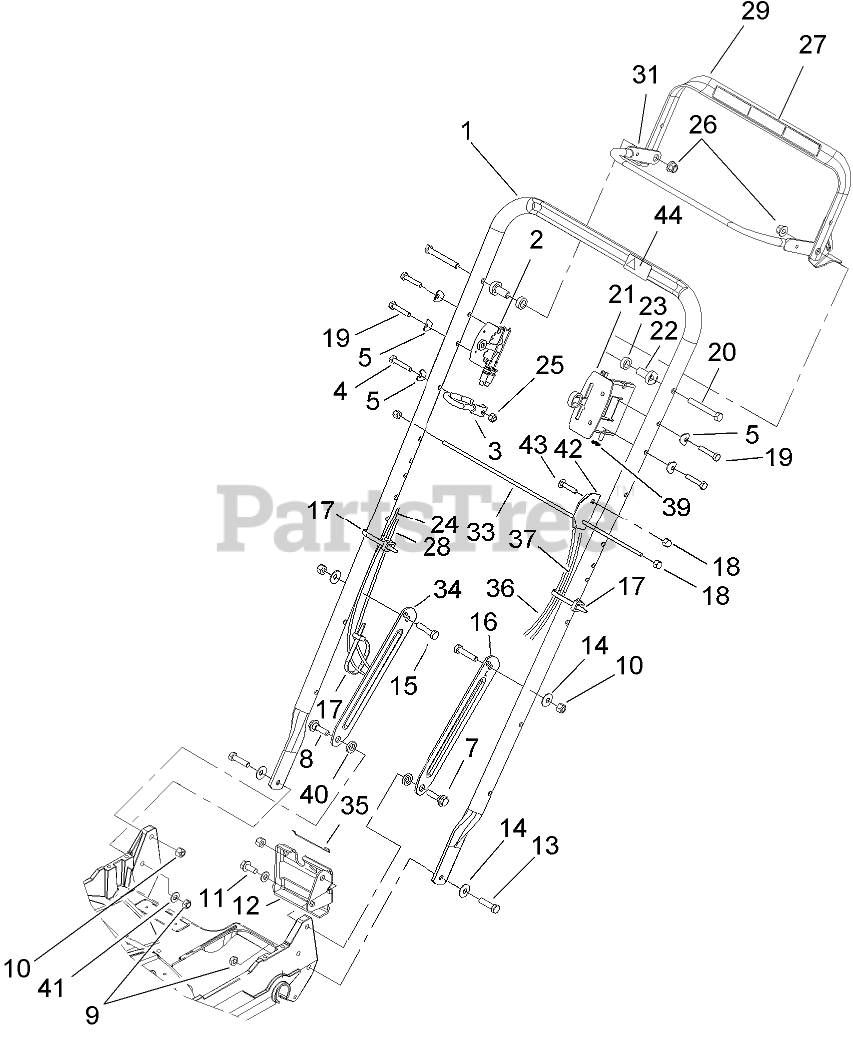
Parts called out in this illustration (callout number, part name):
1	HANDLE-PROLINE
2	CONTROL-SHIFT
3	GUIDE-ROPE
4	SCREW-HH
5	WASHER
7	SCREW-SHOULDER
8	SPACER
9	NUT-LOCK, NI
10	NUT-LOCK, NI
11	SCREW-HWHTF
12	BRACKET-ADJUSTMENT, TRACTION
13	SCREW-HH
14	WASHER-BELLEVILLE
15	SCREW-HH
16	LATCH-HANDLE, LH
17	TIE-CABLE
18	NUT-CAP
19	SCREW-HH
20	SCREW-HH
21	CONTROL-THROTTLE
22	SPACER-SUPPORT
23	SPACER-NYLON
24	CABLE-BRAKE
25	NUT-LOCK, NI
26	NUT-LOCK, NI
27	DECAL-OPERATION
28	CABLE-SHIFT
29	TRACTION BAIL ASM
31	BRAKE BAIL ASM
33	ROD-SUPPORT, BAG
34	LATCH-HANDLE, RH
35	RETAINER-CABLE
36	CABLE-TRACTION
37	THROTTLE CABLE ASM
39	E-RING
40	SCREW-SHOULDER
41	WASHER-PLAIN
42	PLATE-ALIGNING, BAG
43	SCREW-CARR
44	DECAL-PROTECTION, EAR
